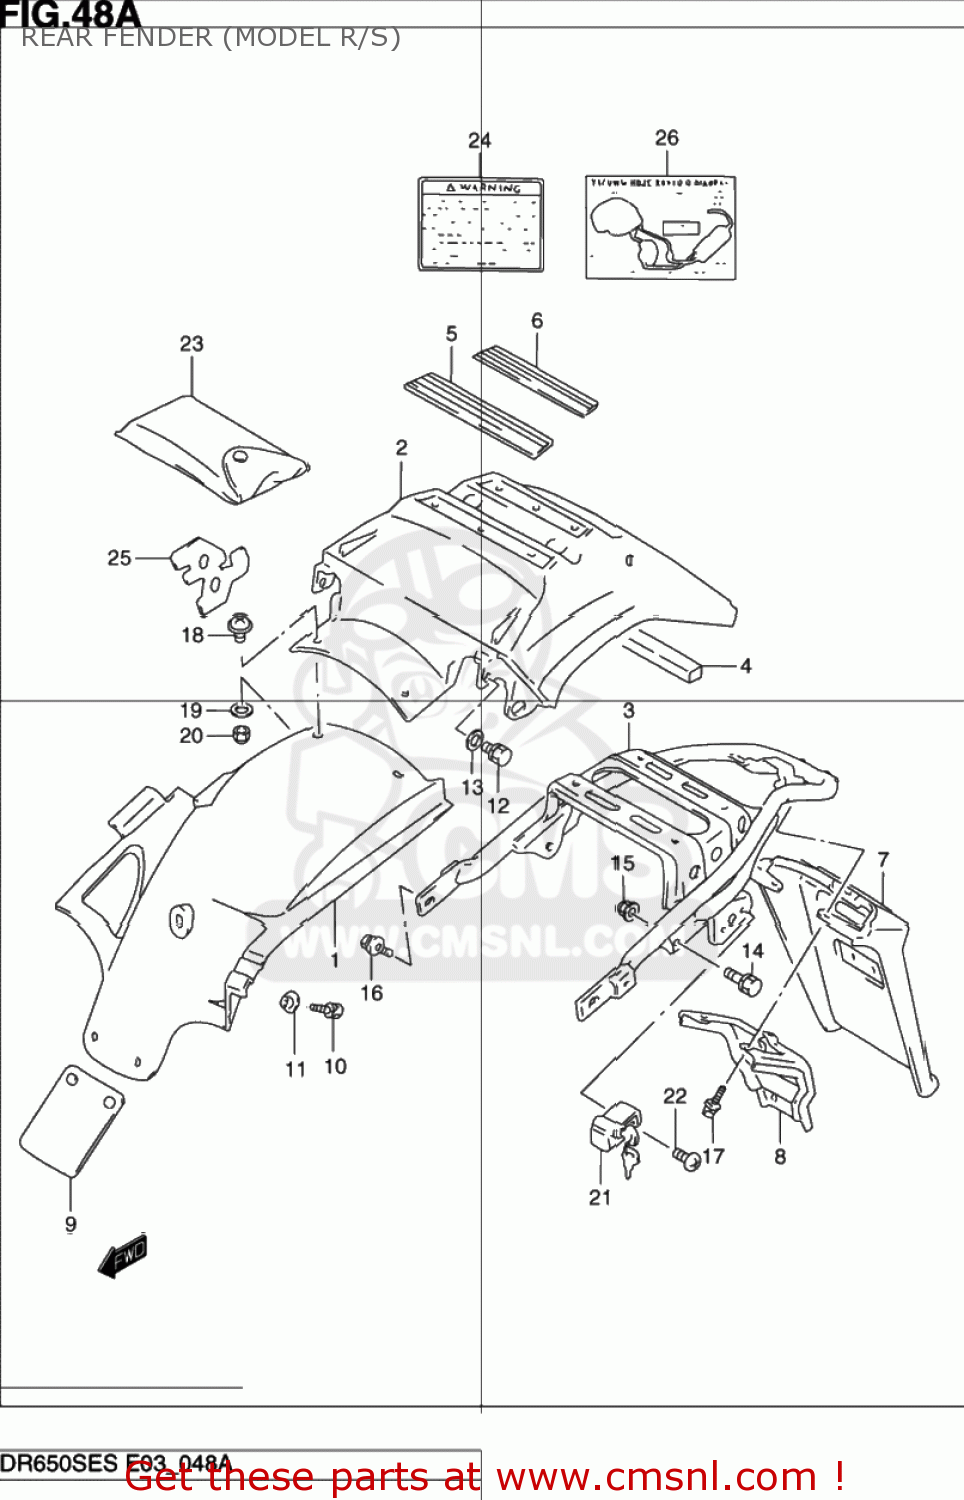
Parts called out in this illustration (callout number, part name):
1	BODY,REAR FENDER,FRONT
2	BODY,RR FENDER RR
3	REINF,RR FENDER
4	CUSHION,REAR FENDER &
5	CUSHION,REAR FENDER,REAR
6	CUSHION,REAR FENDER,REAR
7	EXTENSION,RR FENDER
8	REINFORCEMENT,RR FENDER EXT
9	GUARD,RR FENDER FR MUD
10	BOLT
11	WASHER
12	BOLT
13	WASHER
14	BOLT
15	NUT
16	BOLT
17	BOLT(6X20)
18	SCREW (M5X16)
19	WASHER (5.5X16X1.2)
20	NUT
21	LOCK SET,HELMET
22	SCREW(6X14)
23	TOOL ASSY
24	LABEL
25	SHIELD,REAR FENDER,REAR
26	LABEL (PIPING DIAGRAM)
27	LABEL,TIRE AIR PRESSURE
